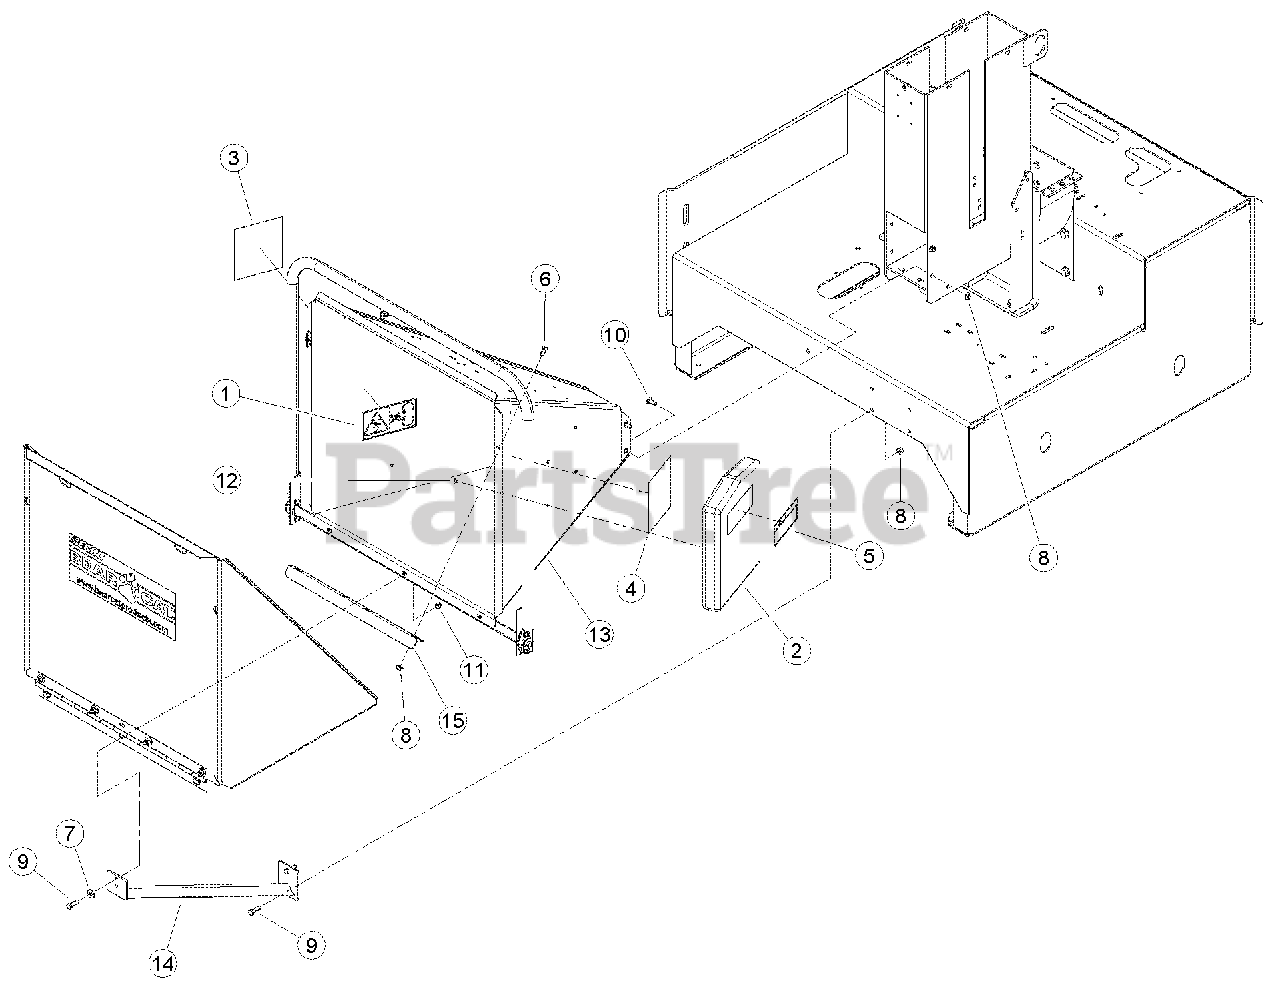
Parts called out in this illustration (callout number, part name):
1	DECAL, BLADE DANGER ISO
2	CONTAINER, INSTRUCTION MANUAL
3	DECAL, FEED POSITION
4	DECAL, FEED POSITION
5	DECAL, MUTILINGUAL MANUAL
6	BOLT, 3/8 X 3/4 HEX HD GR5 ZP
7	WASHER, 3/8 FLAT ZP
8	NUT, 3/8 SERR FLANGE NC ZP
9	BOLT, 3/8 X 1-1/4 HEX HD GR5 ZP
10	BOLT, 3/8 X 1-1/4 CRG GR5 NC ZP
11	NUT, 3/8 NE NYLOCK ZP
12	RIVET, AL BLIND 1/4 X 1/2 DOME HEAD
13	WELDMENT, 5 INCH CHIPPER CHUTE
14	WELDMENT, CHUTE SUPPORT
15	ANGLE, CHUTE BRACE
